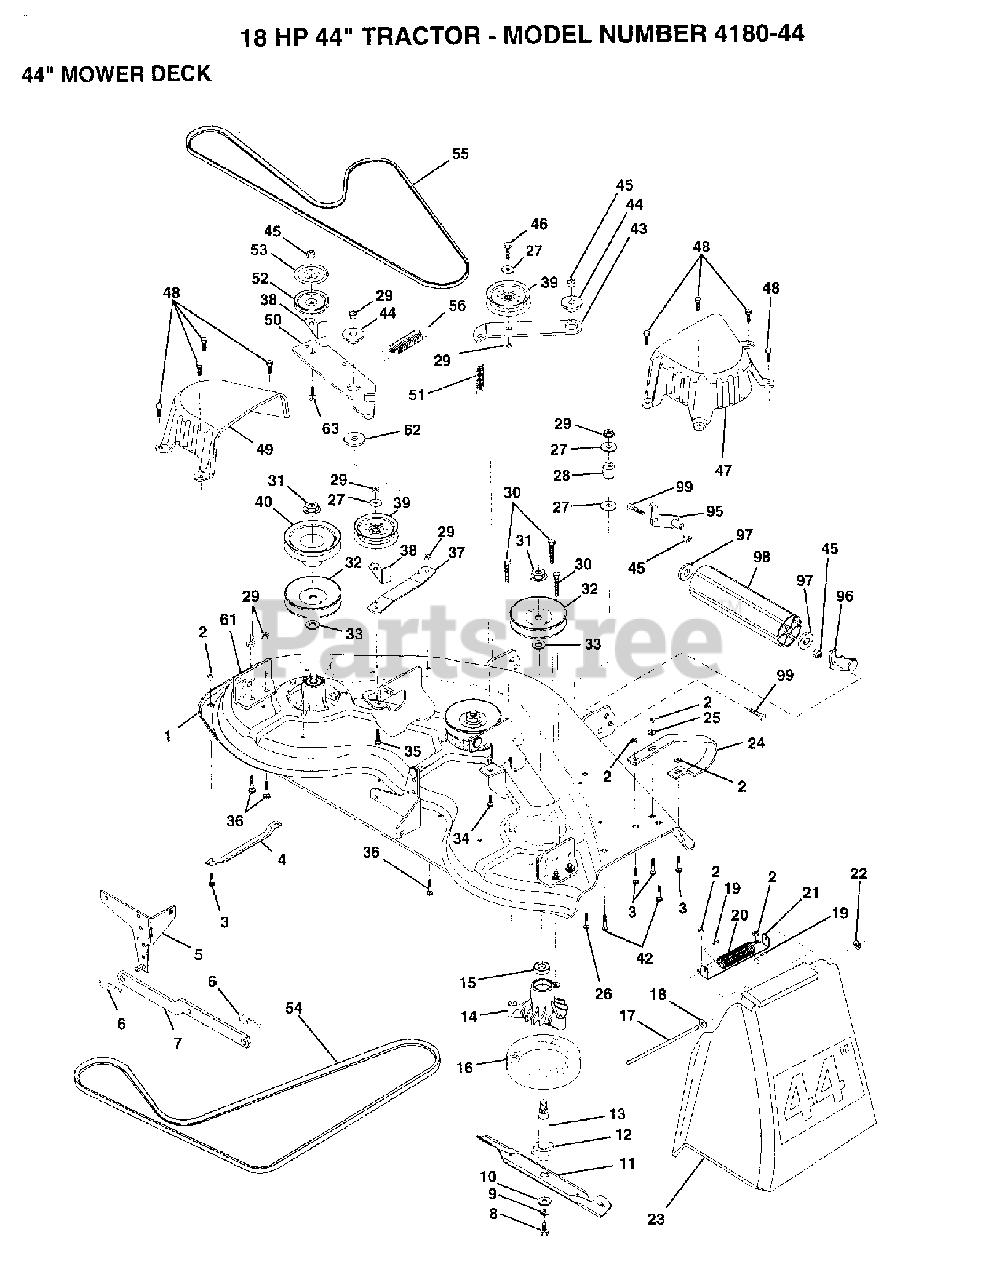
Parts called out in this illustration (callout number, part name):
2	NUT.71038.31-18.HEX.NYLOCK
3	BOLT.5/16-18.
4	RUNNER LH
5	BRACKET SWAY BAR
6	RETAINER SPRING
8	BLADE BOLT
10	WASHER.BLADE
11	44" BLADE-HI PERFORMANCE
12	BEARING.BALL.#6204.(MANDREL)
13	SHAFT.ASM.W/BEARING
14	HOUSING.MANDREL
17	ROD-HINGE T
18	WASHER
19	CAP-SLEEVE LT
20	DEFLECTOR SPRG T
21	BRACKET, DEFLECTOR
22	NUT PUSH M
23	DEFLECTOR SHIELD
24	RUNNER-RH YTV
25	WASHER M
26	BOLT
28	IDLER SPRING SPACER
29	NUT
30	Hex Washer Head Bolt, .313-18 X 1.19
33	WASHER
35	BOLT
37	STIFFENER ARM
39	IDLER-FLAT GT
40	PULLEY.DRIVEN.44"
42	BOLT
43	ARM.IDLER.SEC.44"
45	LOCKNUT
46	BOLT
47	COVER MANDRELL
48	SCREW.1/4-20X5/8
49	COVER.MANDREL.LH.44"
50	ARM.IDLER.PRIMARY
51	SPRING.SEC.44"VEN
52	PULLEY IDLER
53	SHIELD IDLER
55	BELT
61	BRACKET.GUAGE.WHEEL
63	BOLT.3/8-16X1.50
64	WASHER
67	LOCKNUT
95	Roller Bracket Assembly, LH
98	MANUAL, OPERATOR
99	BOLT
